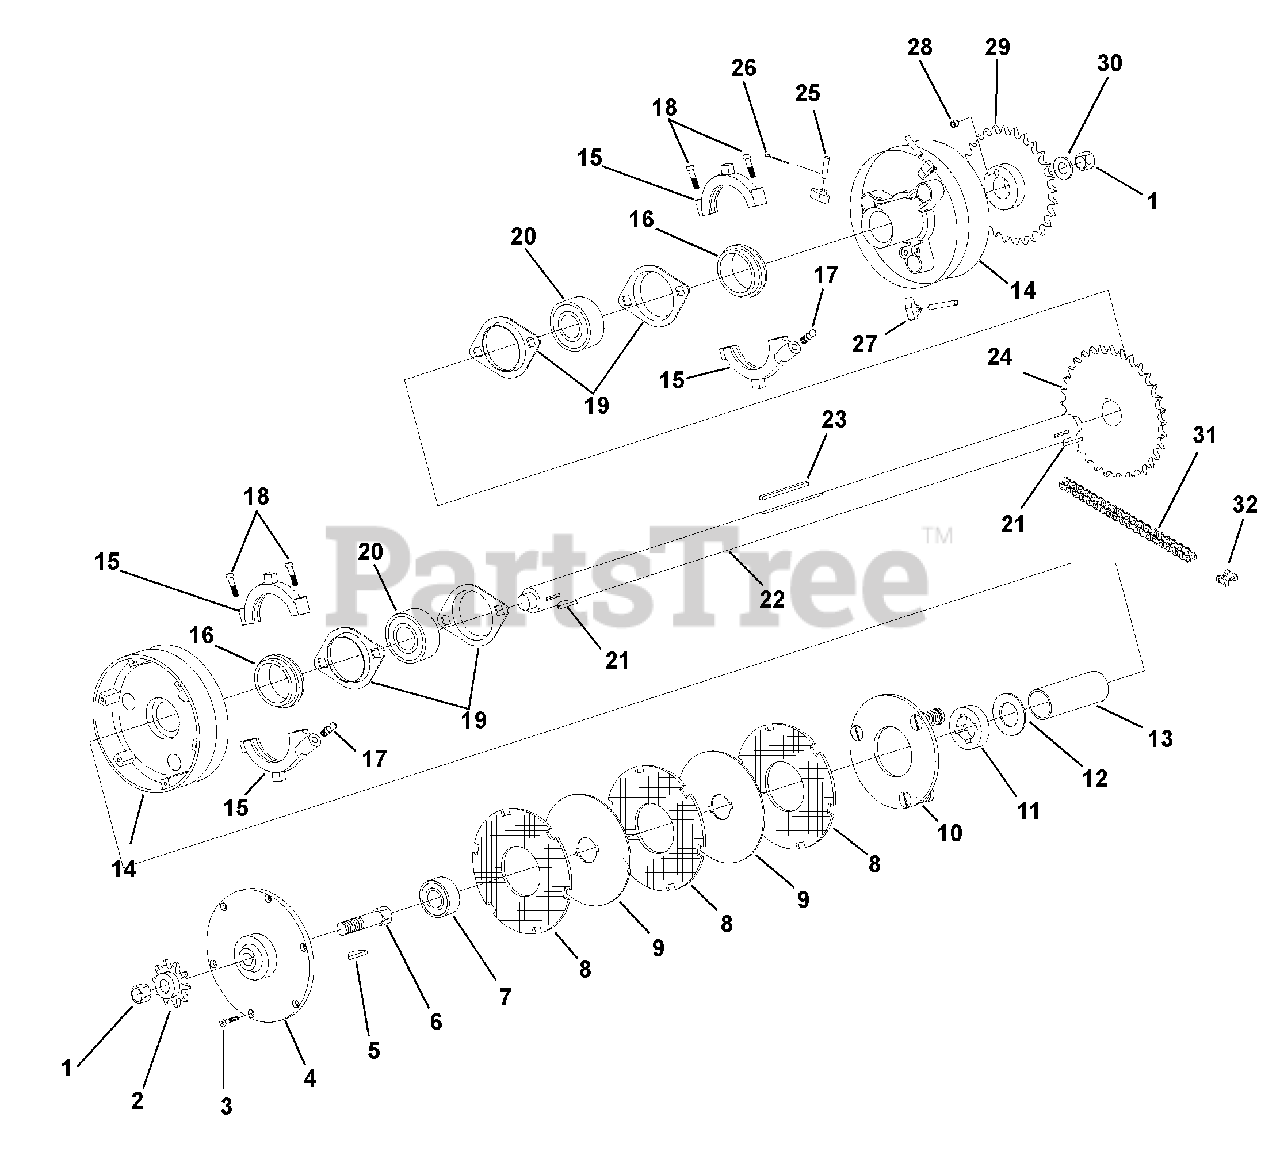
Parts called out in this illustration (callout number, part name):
1	Nut, Hex .50-20
2	Sprocket, 10 Tooth
3	Screw, Flat Head Machine 10-32 x .625 Stainless Steel
4	Cover, Clutch
5	Key, Woodruff .187 x .75
6	Stud, Sprocket
8	Disc, Clutch
9	Plate, Clutch
10	Plate, Pressure #40
11	Retainer, Key
12	Washer, Thrust
13	Bushing, Sintered Iron Copper
14	Assembly, Clutch Housing (Includes Item # 13)
15	Collar, Bronze
16	Cone, Clutch
17	Fitting, Grease .25-28
18	Screw, Phillips Round Head Machine 10-32 x 1
19	Flange, Bearing
21	Key, Woodruff .25 x .875
22	Shaft, Clutch 25-Inch (995310)
23	Key .25 x 2.375
24	Sprocket, 32-Tooth
25	Pin, Clevis .187 x 1
26	Pin, Cotter .062 x .50
27	Clutch Dog
28	Key, Clutch (Brass Bushing Used as Shear Pin)
29	Sprocket, 28-Tooth
30	Washer, Flat
31	Chain, Clutch Shaft (Kohler 31.5" #423)
32	Master Link #423
